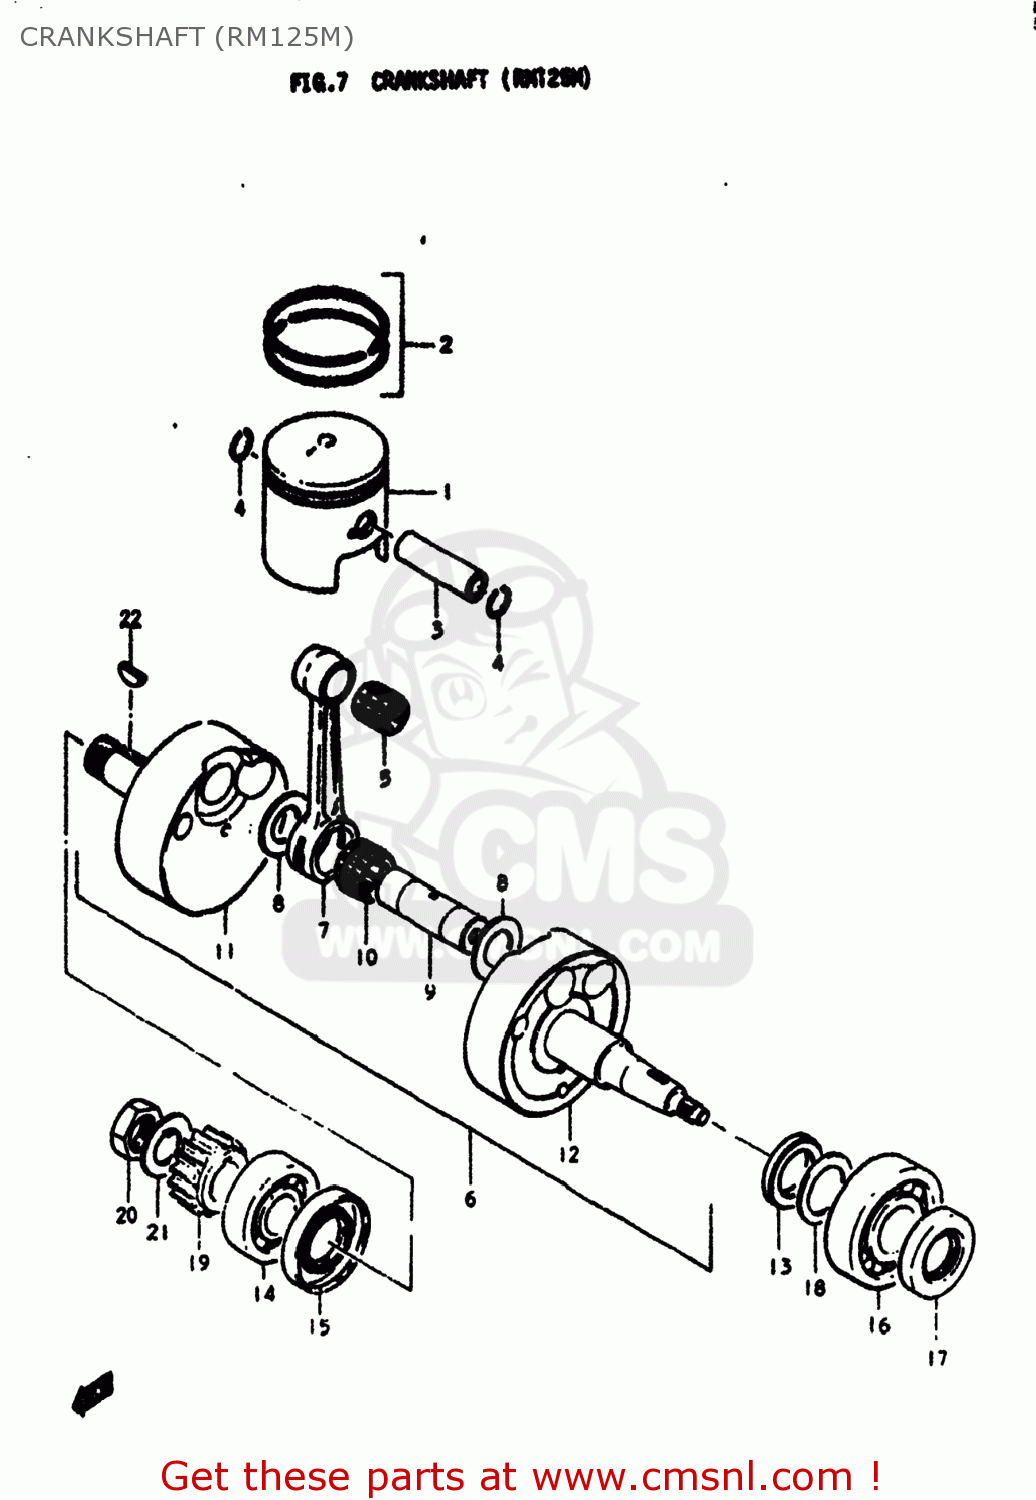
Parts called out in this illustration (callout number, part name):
1	PISTON
2	RING SET,PISTON
3	PIN,PISTON
4	RING,SNAP 14MM
5	BEARING
6	CRANKSHAFT ASSEMBLY
7	CONNECTING ROD
8	WASHER(19X32X1)
9	PIN,CRANK
10	BEARING
11	CRANKSHAFT
12	CRANKSHAFT,LEFT
13	SPACER
14	BEARING
15	SEAL,OIL(26X52X8)
16	BEARING(25X62X17)
17	OIL SEAL
18	SHIM(25X36X0.8)
19	GEAR,PRIMARY DRIVE
20	NUT
21	WASHER
22	KEY
